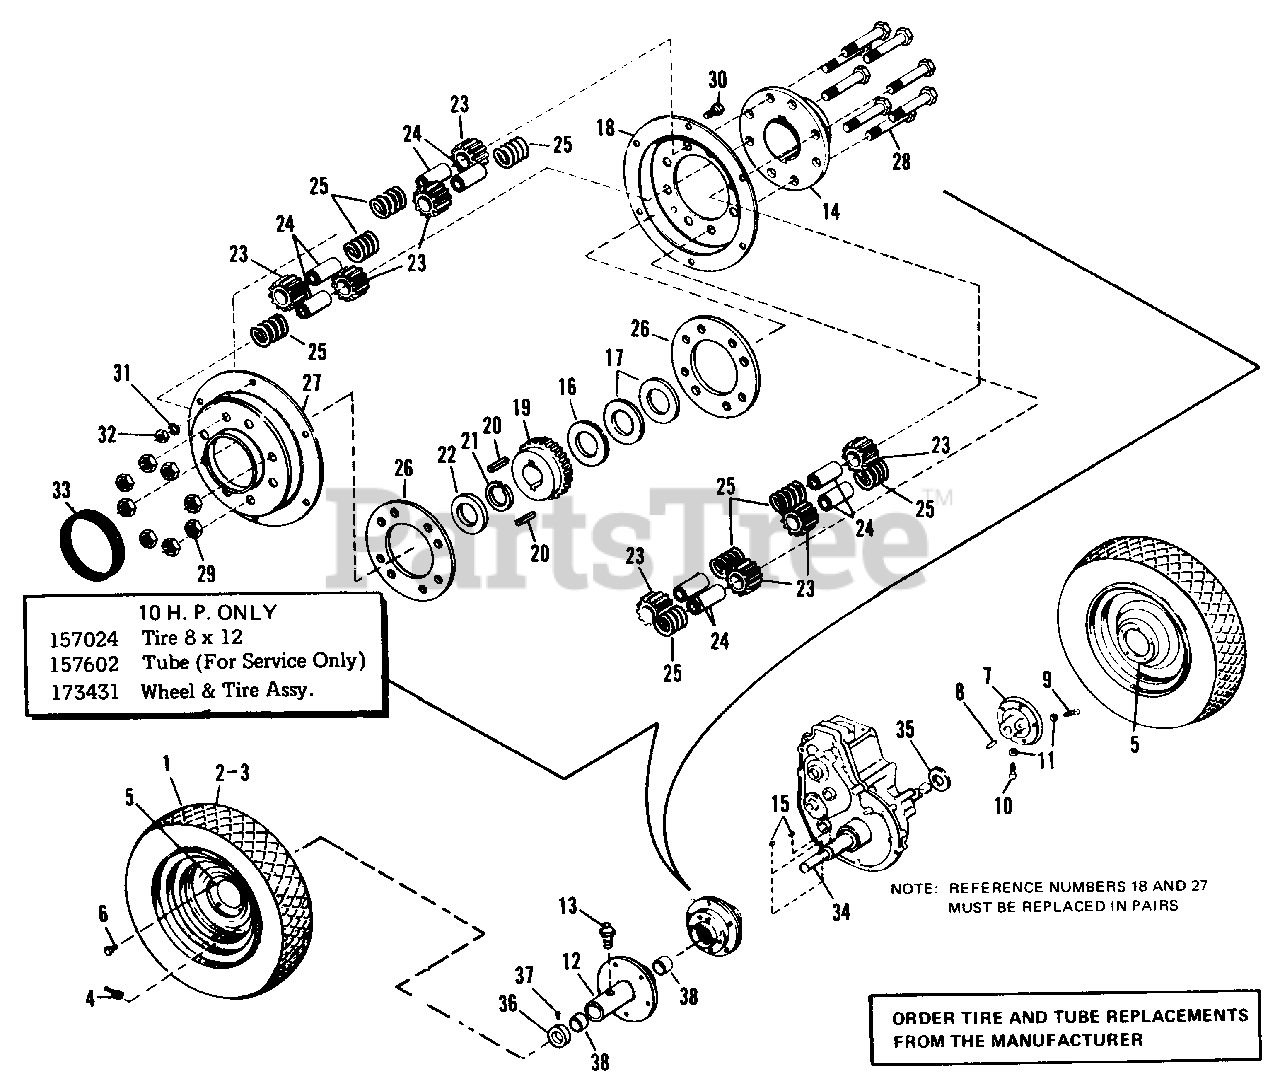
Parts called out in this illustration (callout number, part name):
1	Wheel & Tire Assy.
2	Tire 10-1/2" x 12
4	Valve Stem
5	Wheel Drive
7	L.H. Wheel Hub
9	Set Screw, 3/8"-16 x 1-1/2"
10	Set Screw, 3/8"-16 x 1"
11	Hex Jam Nut, 3/8"-16
12	R.H. Wheel Hub Assy.
13	Grease Fitting
14	Differential Carrier
16	Axle Washer
17	Axle Washer
18	Differential Cover
19	Differential Gear
20	Hi-Pro Key
21	Retaining Ring
22	Axle Washer
23	Differential Pinion
24	Differential Pinion Spindle
26	Ring Spacer
27	Differential Cover
28	Hex Cap Screw, 3/8"-16 x 2-1/2"
29	Full Lock Hex, Nut, 3/8"-16
30	Hex. Cap Screw, 1/3"-20 x 5/8"
31	Lock Washer, 1/4"
32	Full Hex Nut, 1/4"-20
33	Differential Cover Seal
34	Rear Axle
36	Axle Collar
37	Set Screw, 5/16"-18 x 3/8"
38	Tire 8 x 12
38	Tube (For Service Only)
38	Wheel & Tire Assy.
